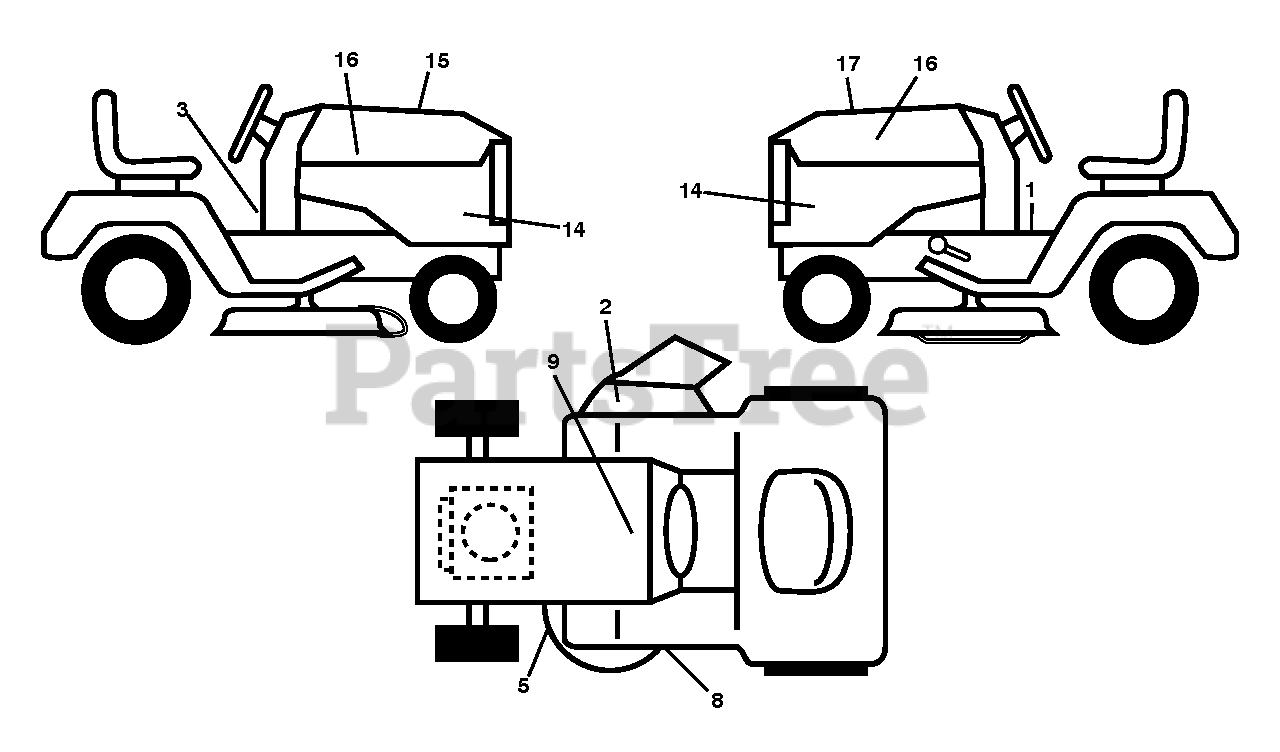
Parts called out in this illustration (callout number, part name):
1	DECAL.FENDER.WARNING.ENGLISH
2	DECAL.MOWER.WARN.KEEP.HAND.AWY
3	DECAL, WARNING SPARK ARRESTOR
5	DECAL.MOWER
8	DECAL.MOWER.SCH.48/54.PREM
9	DECAL BTRY SYMBOLS
14	DECAL.SIDE.PANEL.YTH24K48
15	DECAL.WARNING.CUST.RESP.E85.
16	RP.DECAL.BADGE.170MM.TEXTLOGO
17	Decal, Replacement YTH24K48
